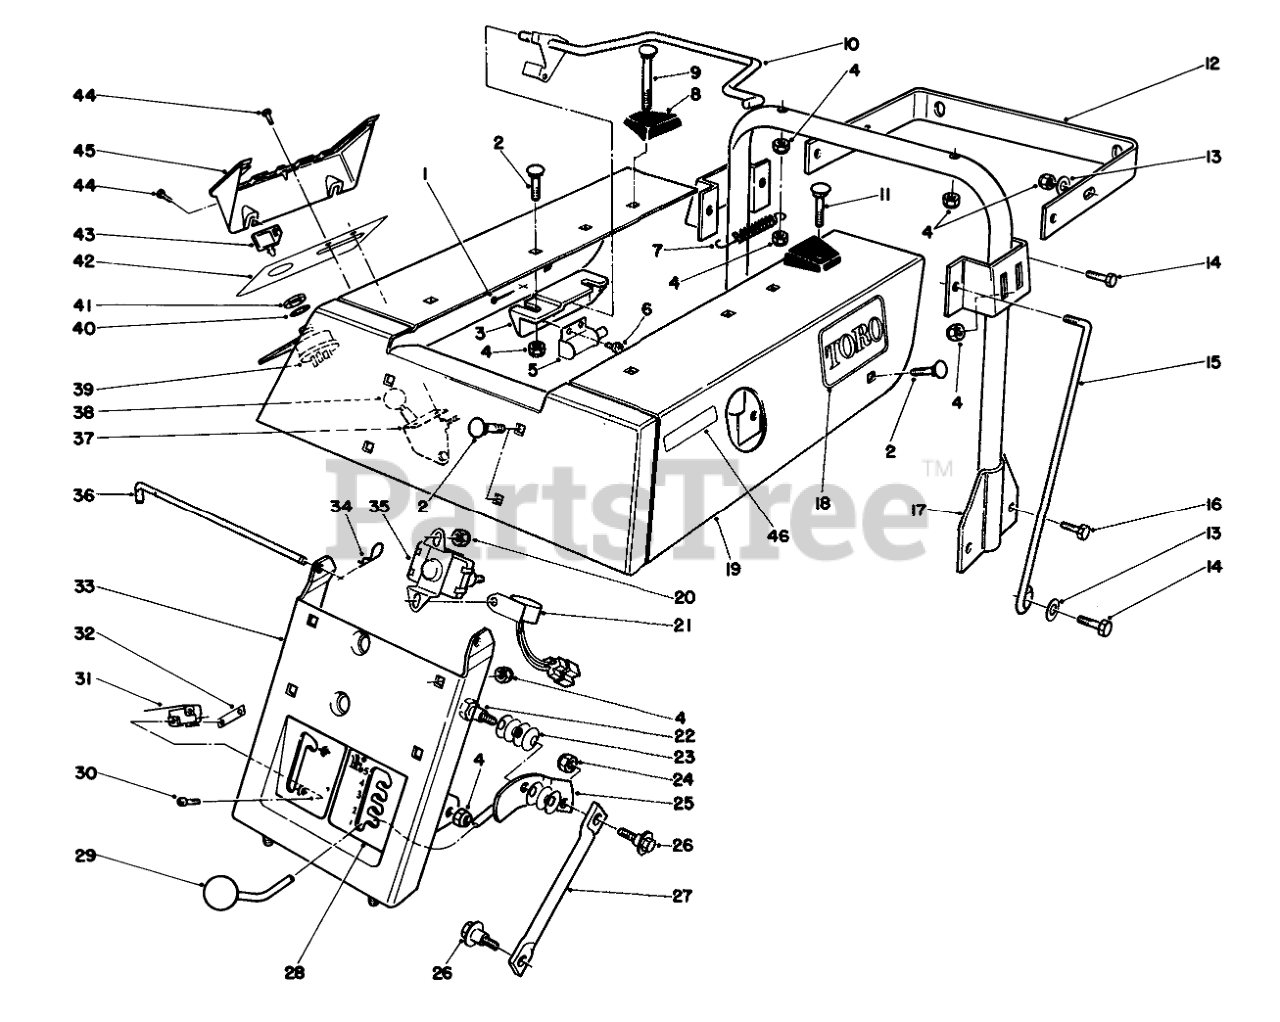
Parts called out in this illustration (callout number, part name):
1	PIN-COTTER
2	SCREW-CARR
3	BRACKET
4	NUT-LOCK, NI
5	INTERLOCK SWITCH
6	#8 X .625" PHILPS PAN H
7	SPRING-IDLER
8	SEATBASE GUARD
9	SCREW-CARR
10	LEVER ROD W A
11	SCREW-CARR
12	Standbar
13	WASHER-PLAIN
14	SCREW-HH
15	BRACE-SEAT SUPPORT
16	SCREW-HH
17	Seat Support W.A.
18	DECAL
19	Body W.A.-Rear
20	NUT-LOCK, NI
21	Module-Interlock
22	BOLT-SHOULDER
23	WASHER-BELLEVILLE
24	NUT-LOCK, NI
25	HOC HDLE WA
26	BOLT-SHOULDER
27	LINK-HOC
28	DECAL - HOC/DECK ENGAGE
29	KNOB-CONTROL
30	SCREW-SPH
31	SWITCH-MICRO
32	NUT-SPEED
33	Support W.A.-Seat
34	PIN-COTTER
35	SOLENOID
36	SEAT BASE ROD
37	Control-Throttle
38	Knob
39	SWITCH-STARTER
40	Washer-Int. Tooth (Incl. with #38)
41	Nut-Hex (Incl. with #38)
42	DECAL - CONTROL PANEL
43	KEY-IGNITION
44	SCREW-THD FORM, HWH
45	COVER-CONTROL PLATE
46	DECAL - CHECK OIL
